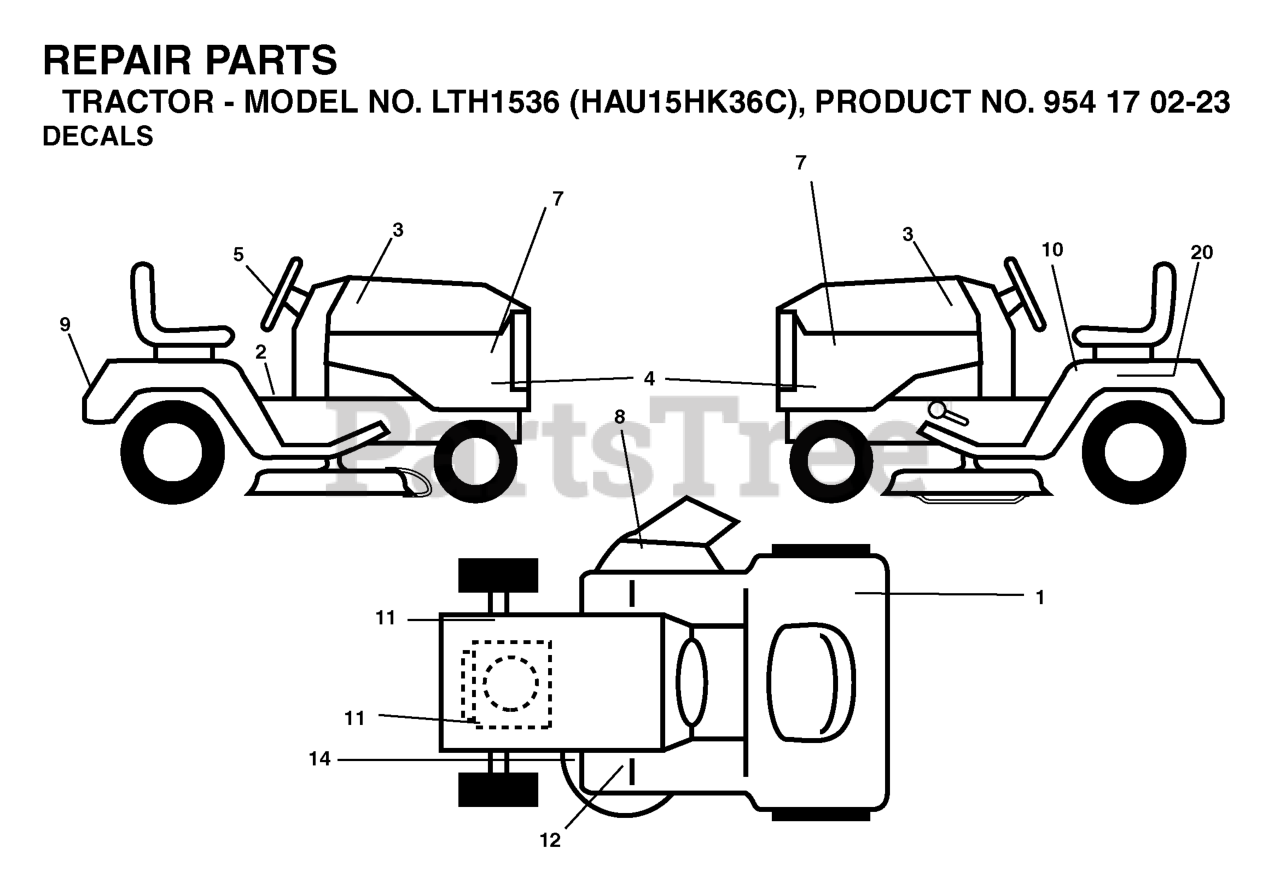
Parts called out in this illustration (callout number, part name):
1	DECAL
2	DECAL PARK BRAKE
5	DECAL.STEERING.HUSQ.BLUE
7	DECAL.HOOD.HUSQVARNA.INTERNATI
8	DECAL.INTERNATIONL.CUTFINGER
10	DECAL READ OWNER'S MAN SYMS
12	DECAL
14	DECAL V-BELT SCHEMATIC
20	DECAL BTRY SYMBOLS
